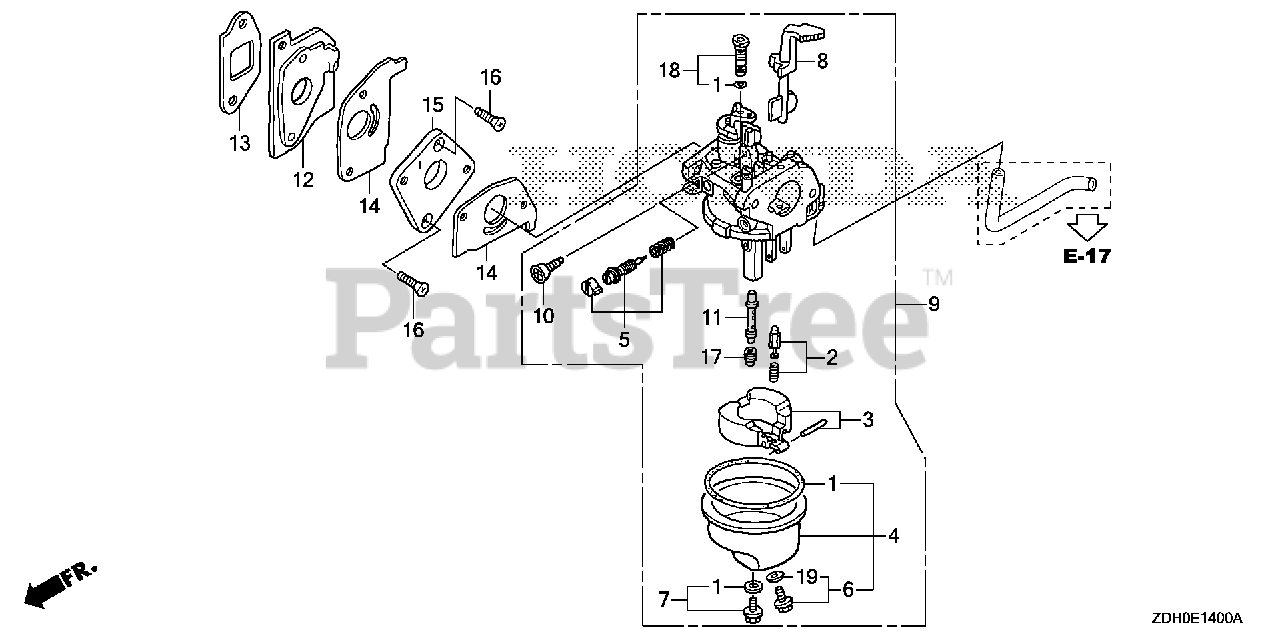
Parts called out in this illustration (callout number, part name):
1	GASKET SET (CARBURETOR NO.)
2	VALVE SET, FLOAT (CARBURETOR NO.) (SEAT NOT INCLUDED)
4	CHAMBER SET, FLOAT (CARBURETOR NO.)
5	SCREW SET
6	SCREW SET, DRAIN (Honda Code 1672187). (CARBURETOR NO.)
7	SCREW SET (CARBURETOR NO.)
8	CHOKE SET (CARBURETOR NO.)
9	CARBURETOR ASSY. (BF24N A)
10	SCREW, THROTTLE STOP
11	NOZZLE, MAIN (CARBURETOR NO.)
12	INSULATOR, CARBURETOR
13	GASKET, INSULATOR (ENGINE NO.)
14	GASKET, CARBURETOR
15	PLATE, CARBURETOR JOINT
16	SCREW, FLAT (5X20)
17	JET, MAIN (#48) (CARBURETOR NO.)
17	JET, MAIN (#50) Use from Engine SN BF12A B.
17	JET, MAIN (#52) Use from Engine SN BF12A B.
18	JET SET, PILOT (#35)
19	WASHER, PLAIN (6.2X10.7 DRAIN) (CARBURETOR NO.)
